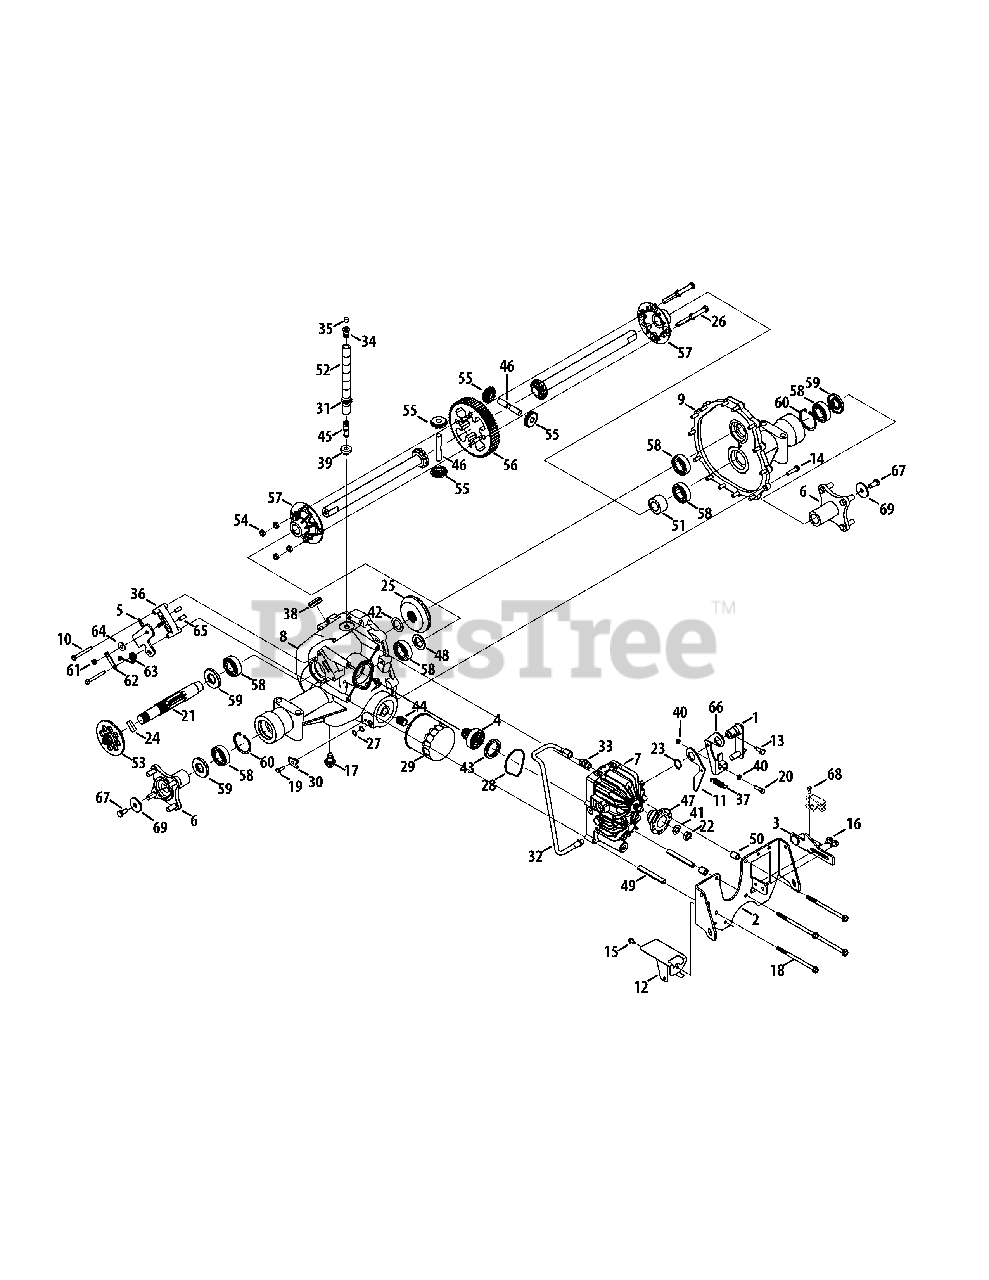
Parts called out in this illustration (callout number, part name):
1	Neutral Return Arm Assembly
2	Torq Bracket Assembly
3	Neutral Return Arm Assembly
4	Pinion Gear, 13T
5	Brake Arm Actuator
6	Wheel DD Hub Assembly
6	Wheel SPINE Hub Assembly
7	Pump Assembly
8	RH Housing
9	LH Housing
10	Hex Washer Screw, 1/4-20 x 2.375
11	Neutral Arm, LH
12	Hydro Dump Spring Plate
13	Hex Screw, 5/16-24 x .625
14	Hex Lock Screw, 5/16-18 x 1.25
15	Hex Washer Screw, 1/4-20 x .500
16	Hex Washer Screw, 5/16-18 x .500
17	Plug Screw, M14 x 1.5 x .827
18	Hex Washer Screw, 5/16-18 x 5.350
19	Hex Screw, 1/4-20 x .75
20	Hex Screw, 1/4-20 x 1.00
21	Output Shaft, 9T
22	Jam Lock Nut, 1/2-20
23	Retaining Ring, .875
24	Brake Pad
25	Bevel Gear, 54T
26	Hex Screw, 3/8-16 x 2.00
27	0-Ring, .426 x .566 x .070
28	Gland Seal
29	Oil Filter
30	Tube Clamp, .500
31	Fuel Clamp
32	Hydro Pick-Up Tube
33	Straight Fitting
34	Plastic Vent
35	Plastic Vent Cap
36	Brake Yoke
37	Extension Spring, .50 x 1.98
38	Rubber Grommet, .750 x 1.063 x .4375
39	Grommet, .362 x .56 x .63
40	Jam Nut, 1/4-20
41	Bell Washer, .525 x 1.00 x .050
42	Thrust Washer, 1.007 x 1.542 x .03
43	Spring Washer, 1.595 x 2.011 x .030
44	Filter Nipple Fitting
45	Tube Fitting, .500
46	Shaft, .500 x 3.005
47	Hydro Pump Adapter
48	Axle Spacer, 1.007 x 1.665 x .141
49	Hydro Spacer, .323 x .443 x 3.51
50	Hydro Spacer, .323 x .600 x .740
51	Axle Spacer, 1.007 x 1.665 x .989
52	Fuel Line, 1/2
53	Disc Brake
54	Jam Lock Nut, 3/8-16
55	Miter Gear
56	Spur Gear
57	RH Housing Differential
58	Ball Bearing, 1 x 52 x 15
59	Oil Seal, 1.00 x 2.047 x .2755
60	Retainer Ring
61	Hex Lock Nut, 5/16-24
62	Anti-Rotation Brake Bracket
63	Torsion Spring, .75 x 3
64	Flat Washer, .343 x .880 x .062
65	Brake Actuator Pin
66	Neutral Arm
67	Hex Cap Screw, 3/8-16 x .750
67	Nut, Hex, 3/4-16
68	Shoulder Screw, 10-32 x .500
69	Flat Washer, .390 x 1.50 x .134
